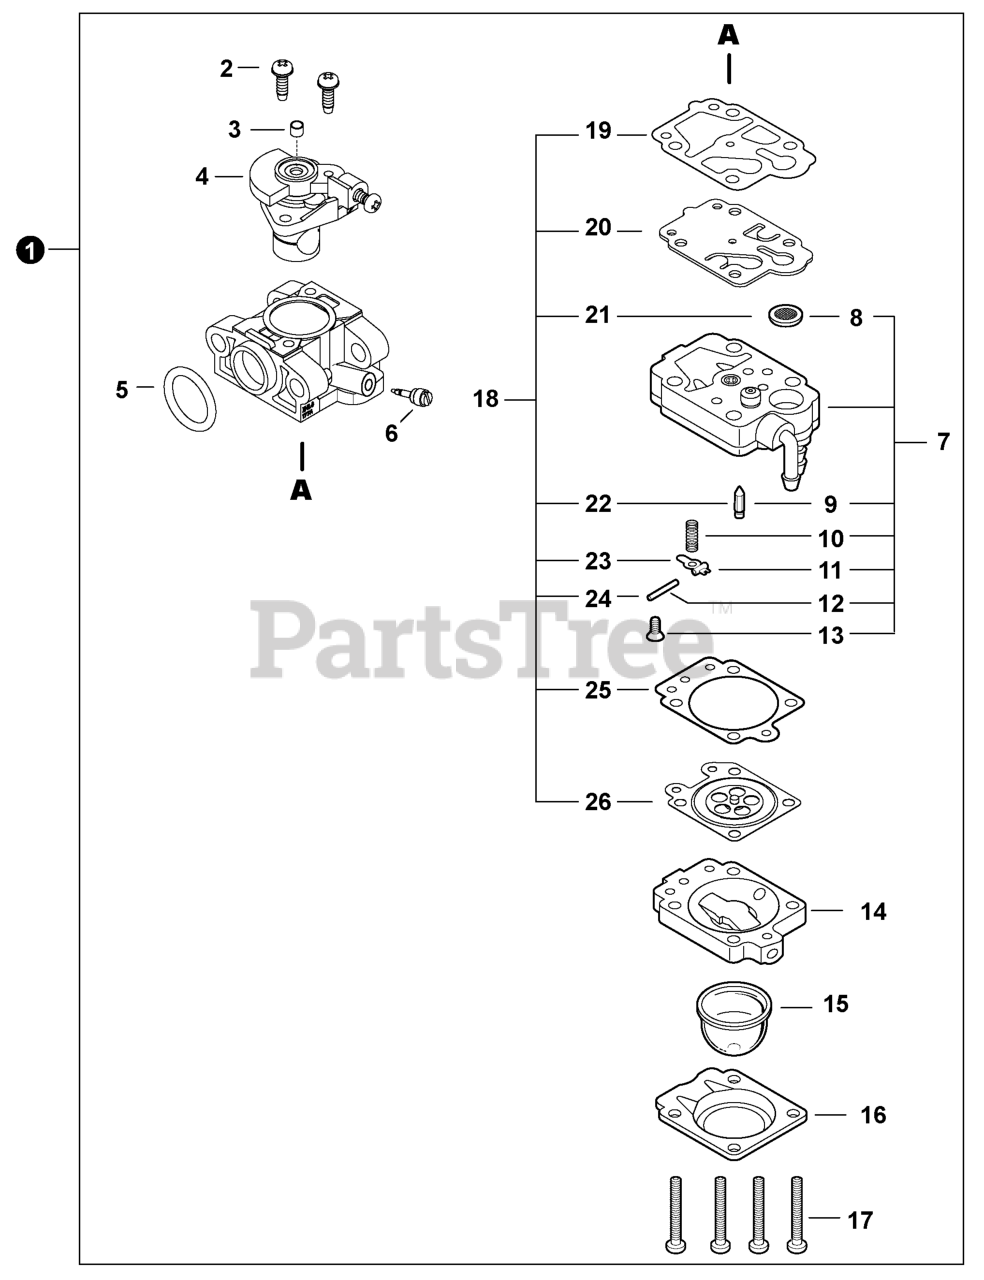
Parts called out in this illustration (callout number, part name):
1	CARBURETOR - HLI GL-9
2	SCREW, THROTTLE COLLAR
3	PLUG
4	VALVE ASSY, THROTTLE
6	NEEDLE, HIGH SPEED
7	BODY ASSY, PUMP
8	SCREEN, FUEL INLET
9	VALVE, INLET NEEDLE
10	SPRING, METERING LEVER
11	LEVER, METERING
12	PIN, METERING LEVER
13	SCREW
14	BODY ASSY, PURGE
15	BULB, PURGE
16	RETAINER, PURGE BULB
18	REPAIR KIT, CARBURETOR
19	GASKET, FUEL PUMP
20	DIAPHRAGM, FUEL PUMP
21	SCREEN, FUEL INLET
22	VALVE, INLET NEEDLE
23	LEVER, METERING
24	PIN, METERING LEVER
25	GASKET, METERING DIAPHRAGM
26	DIAPHRAGM, METERING
